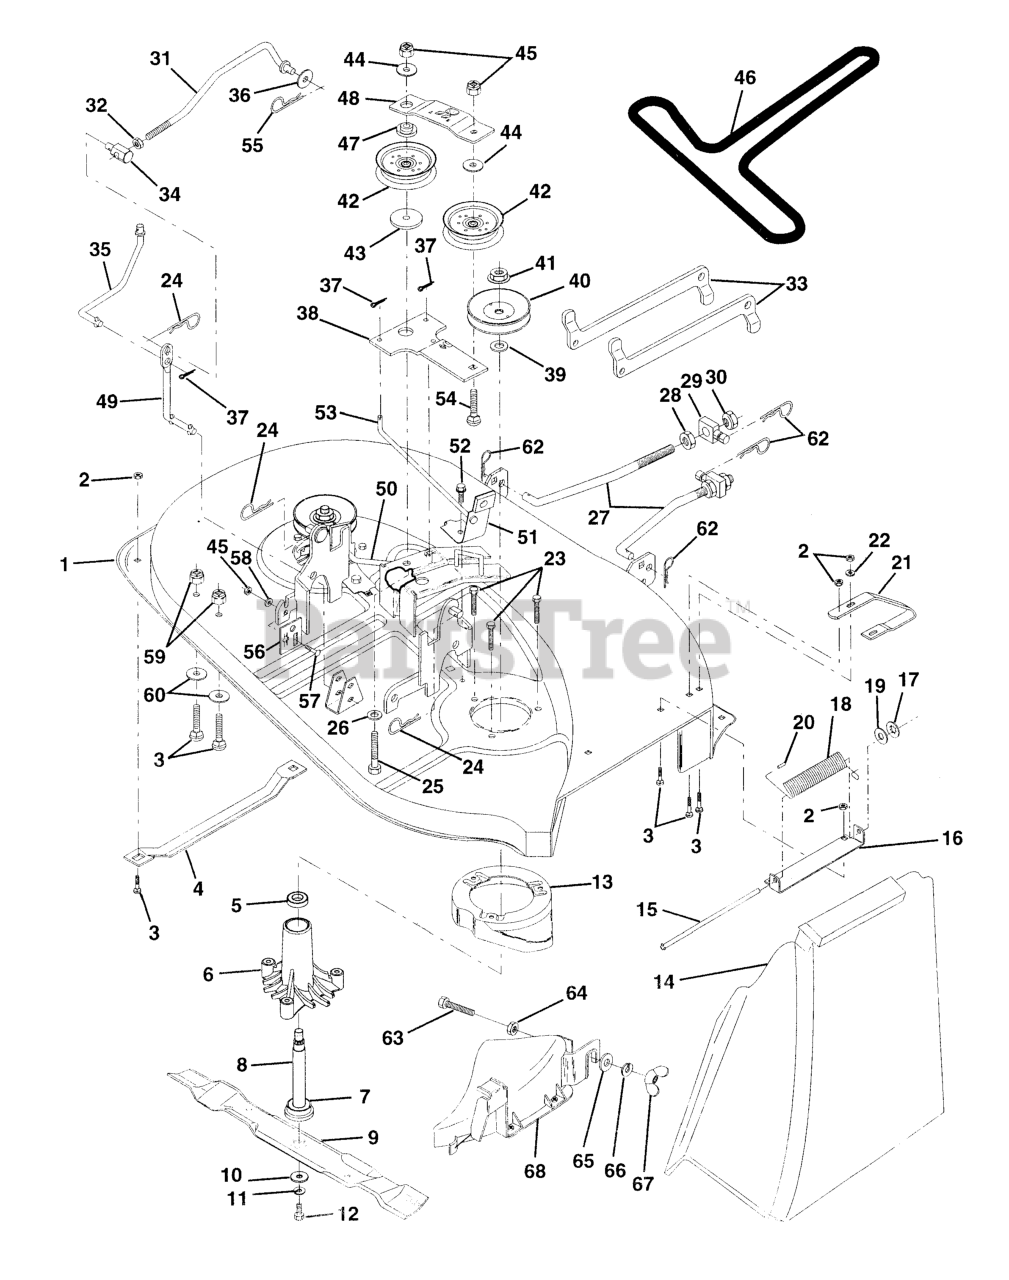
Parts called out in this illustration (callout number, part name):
1	DECK ASS'Y
2	LOCKNUT
3	RP BOLT 5/16-18 X3/4 ZN/YEL GR
4	RUNNER-LH M
6	HOUSING.MANDREL.VENTED (MACHD)
7	BEARING.BALL.#6204.(MANDREL)
8	SHAFT ASM VENT
9	BLADE 38" V MULCH
10	WASHER
11	LOCKWASHER
12	BLADE BOLT
13	STRIPPER
14	SHIELD.DEFLECTOR.MOWER.38.BL
15	ROD-HINGE T
16	BRACKET, DEFLECTOR
17	NUT PUSH M
18	DEFLECTOR SPRG T
19	Washer 11/32 x 5/8 x 16 Gauge
20	CAP-SLEEVE LT
21	RUNNER.RH.38
22	WASHER M
23	BOLT 5/16X18X1 1/4
24	RETAINER-SPRNG RB
25	BOLT
26	WASHER GT
27	LINK ASM FRONT
28	NUT.HEX.JAM.1/2-13
29	TRUNION
30	NUT.LK.W/WSH.1/2.
32	NUT
33	ARM REAR SUSPENSION
35	CLUTCH ROD
36	WASHER
37	COTTER PIN
38	IDLER ARM
39	WASHER
40	MANDREL PULLEY
41	NUT FLANGELOCK 9/16
42	FLAT IDLER PULLEY
43	SPACER RETAINER
44	WASHER GT
46	BELT
47	SPACER.IDLER.ARM
48	STIFFENER.IDLER.ARM
50	BRAKE ROD LH
51	BRAKE ASSEMBLY
52	SCREW.THDROL.5/16-18X3/4.TTY
53	BRAKE ROD RH
55	RETAINER M
56	ADJUSTMENT PLATE
57	Bolt, Carriage 3/8-16 x 3/4
58	WASHER T
59	NUT.71038.31-18.HEX.NYLOCK
62	SPRING RETAINER
63	Bolt, Hex Head 3/8-16 x 1-1/4
64	LOCKNUT
65	WASHER
66	WASHER, LOCK 3/8
68	COVER.MULCHING.38" (2 2)
68	KIT.MANDREL.ASM.3.BOLT
68	DECK ASSEMBLY 38"
